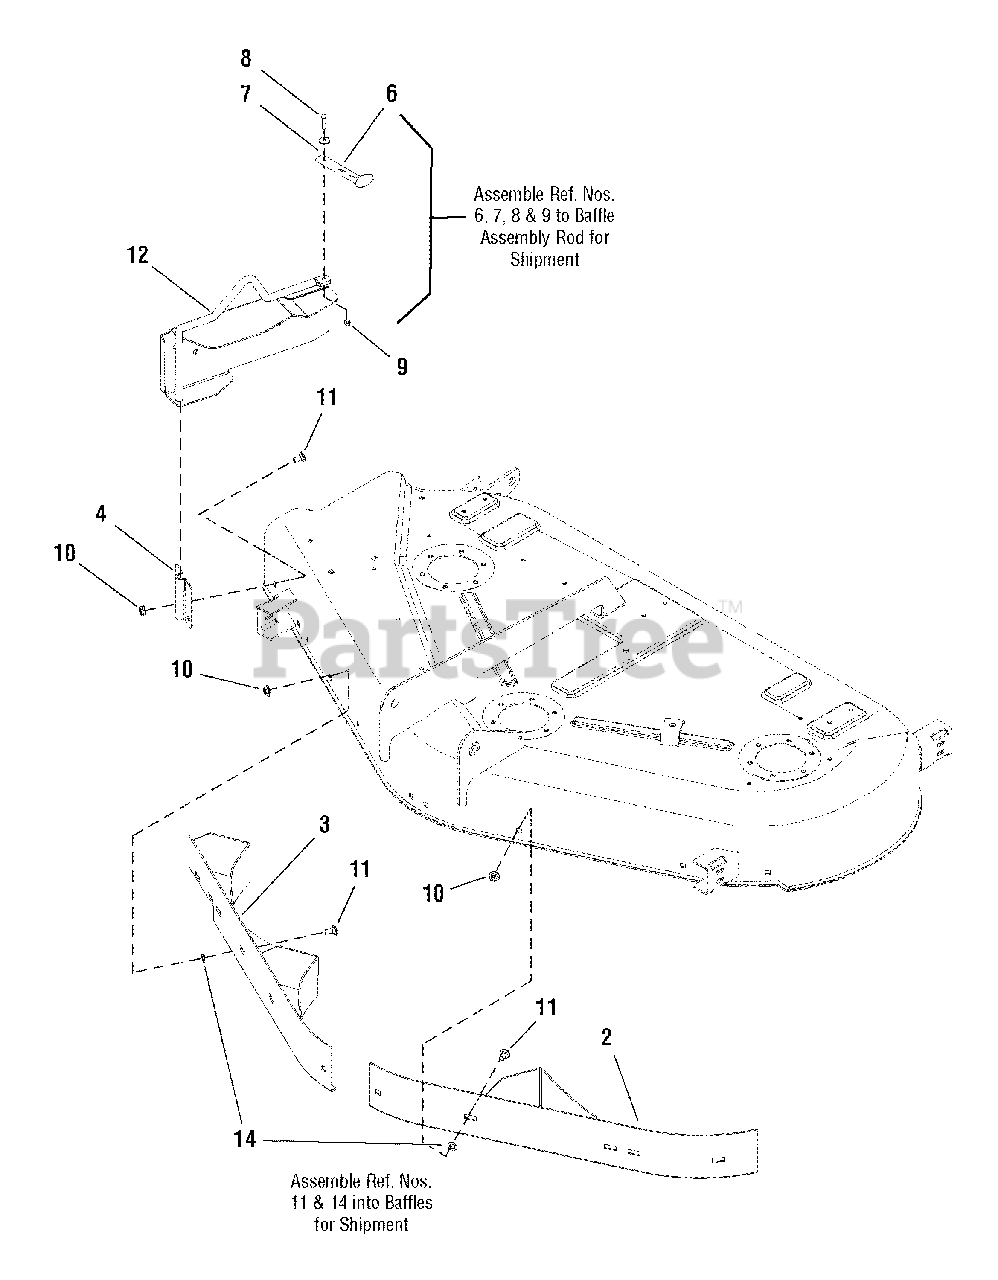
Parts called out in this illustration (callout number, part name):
2	BAFFLE & DEFLECTOR ASSEMBLY, L.H. 44"
2	BAFFLE & DEFLECTOR ASSEMBLY, L.H. 50"
3	BAFFLE & DEFLECTOR ASSEMBLY, R.H. 44"
4	PLATE, Chute Rod
6	STRAP
7	WASHER, Flat, 3/16
8	SCREW, Truss Head, 10-24 x 1
9	NUT, ESNA, 10-24
10	NUT, Whiz Lock, 5/16-18
11	BOLT, Carriage, 5/16-18 x 5/8
12	BAFFLE ASSEMBLY, Mulcher 44"
12	BAFFLE ASSEMBLY, Mulcher 50"
14	NUT, Push, 5/16
